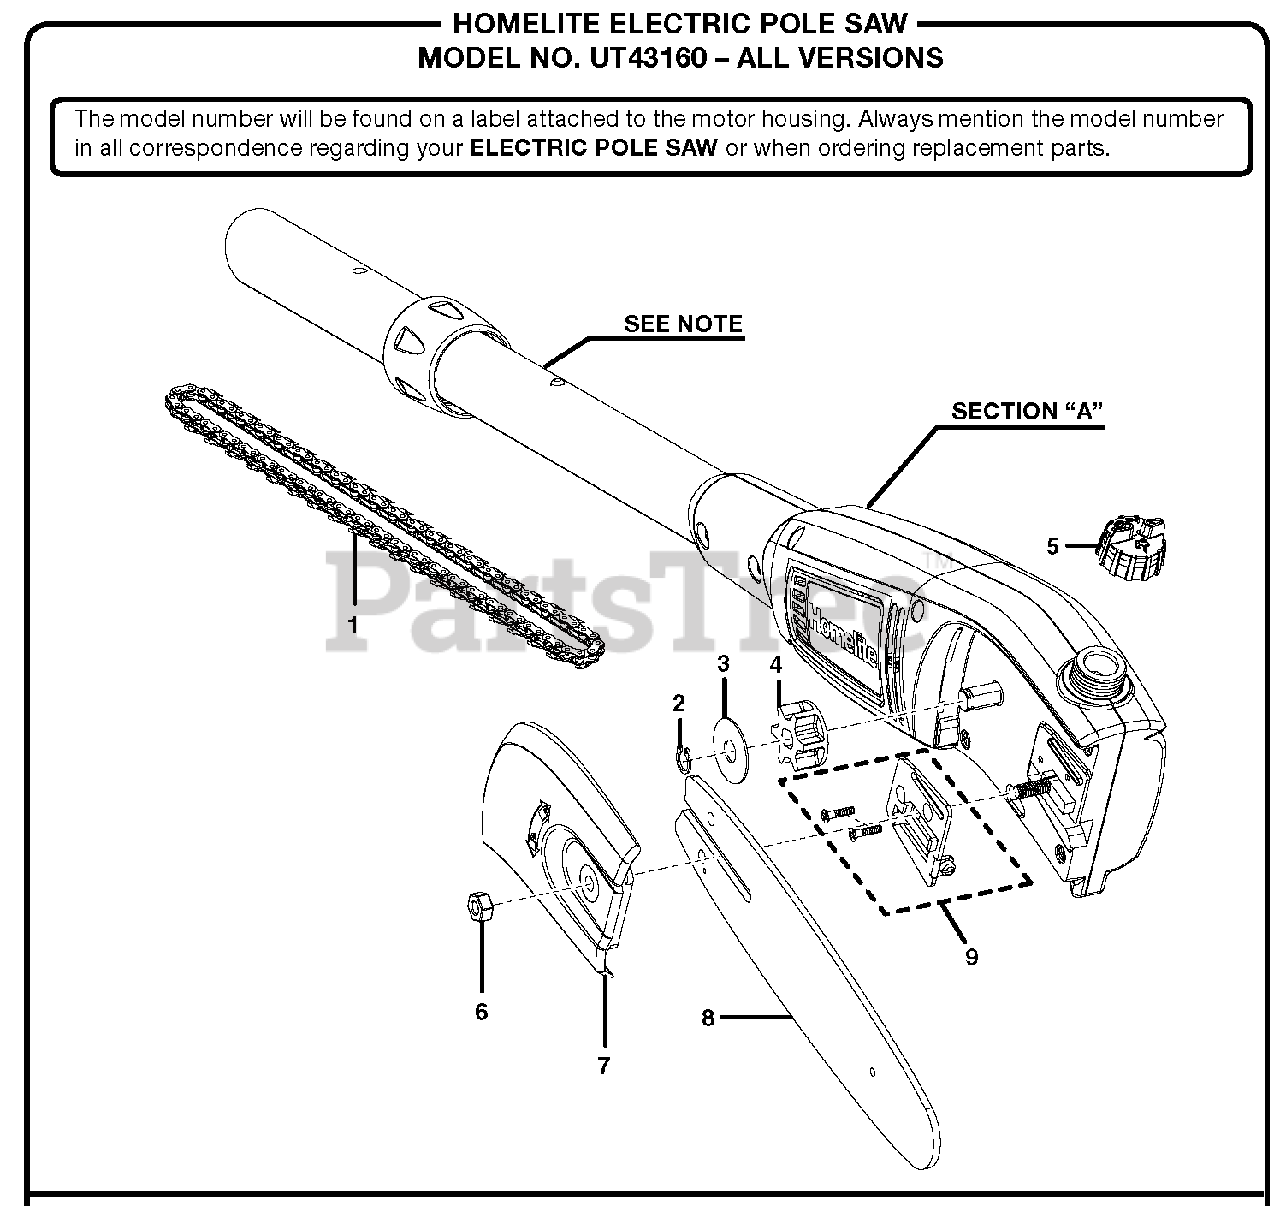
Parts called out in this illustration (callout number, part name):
2	Retaining Ring
6	Hex Nut (M6)
7	Chain Cover Assembly
9	Chain Adjustment Assembly
